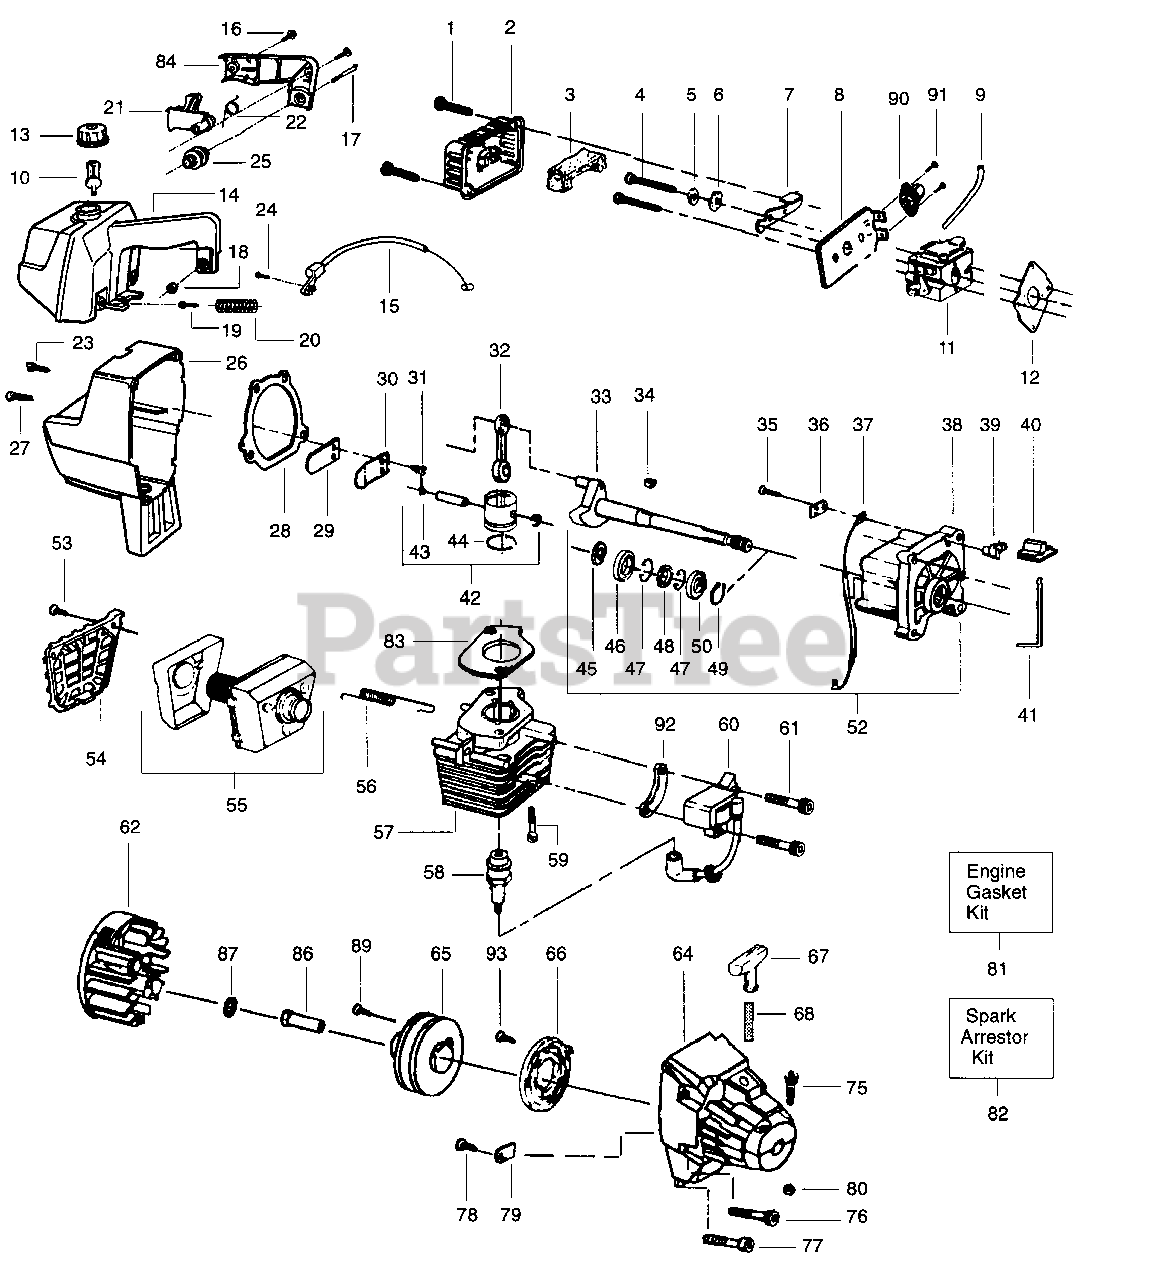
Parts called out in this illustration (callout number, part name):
2	Air Filter Cover
3	Air Filter
6	Wave Washer
7	Choke Shutter
8	Air Filter Plate - Type 1
8	Air Filter Plate - Type 2-3 & Model GTI16D
9	Fuel Line
9	Return Line - Type 2-3 & Model GTI16D
10	Fuel Pick-up Ass'y.
11	Carburetor - WA-217 - Type 1
11	Carburetor - WA-219B - Type 2-3 & Model GTI16D
12	Carburetor Gasket
13	Fuel Cap Ass'y.
14	Handle & Tank Ass'y - Type 1
14	Handle & Tank Ass'y - Type 2-3 & Model GTI16D
15	Throttle Cable Ass'y. - Type 1
15	Throttle Cable Ass'y. - Type 2-3 & Model GTI16D
16	Screw
17	Shoulder Bolt
20	Rear Isolator Spring
21	Throttle Trigger
22	Throttle Spring
23	Screw
25	Isolator
28	Gasket-C'case/Shroud
30	Reed Stop
32	Connecting Rod Ass'y.
33	Crankshaft Ass'y. See Service Ref. 1
34	Flywheel Key
36	Switch Insulator
37	Lead Wire
38	Crankcase Ass'y. (Incl. 46-48 & 50)
39	Switch Ramp
40	Switch Button
41	Switch Spring
42	Piston Kit (Incl. 43,44 & pin),Models GTI 16, GTI 16 SUPER & GTI 16D
42	Piston Kit (Incl. 43,44 & pin) Model GTI 17LE
43	Piston Pin Retainer
44	Piston Ring, Models GTI 16, GTI 16 SUPER & GTI 16D
44	Piston Ring, Model GTI 17LE
46	Inner Bearing
47	Retaining Ring
48	Crankshaft Seal
49	Retaining Ring
50	Outer Bearing
52	Crankcase & Crankshaft Ass'y. (Incl. 33, 38 & 46-50)
54	Muffler Guard
55	Muffler Kit
56	Muffler Spring
57	Cylinder, Models GTI 16, GTI 16 SUPER, GTI 16D
57	Cylinder, Model GTI 17LE
58	Spark Plug, - Type 1
58	Spark Plug, - Type 2-3 & Model GTI16D
60	Ignition Module Kit
61	Screw
62	Flywheel Ass'y.
64	Fan Housing
65	Starter Pulley (Incl. 90)
66	Starter Spring
67	Starter Handle
68	Rope Kit
79	Pulley Retainer
81	Engine Gasket Kit (Inc. 12,28,83)
82	Spark Arrestor Kit
83	Cylinder Gasket
84	Handle Cover
86	Drive Coupling
89	Screw-Pulley
90	Primer Ass'y. - Type 2-3 & Model GTI16D
91	Screw-Prim. - Type 2-3 & Model GTI16D
92	Spacer, Model GTI 17LE
93	Screw-Starter Spring - Type 3 & Model GTI16D
